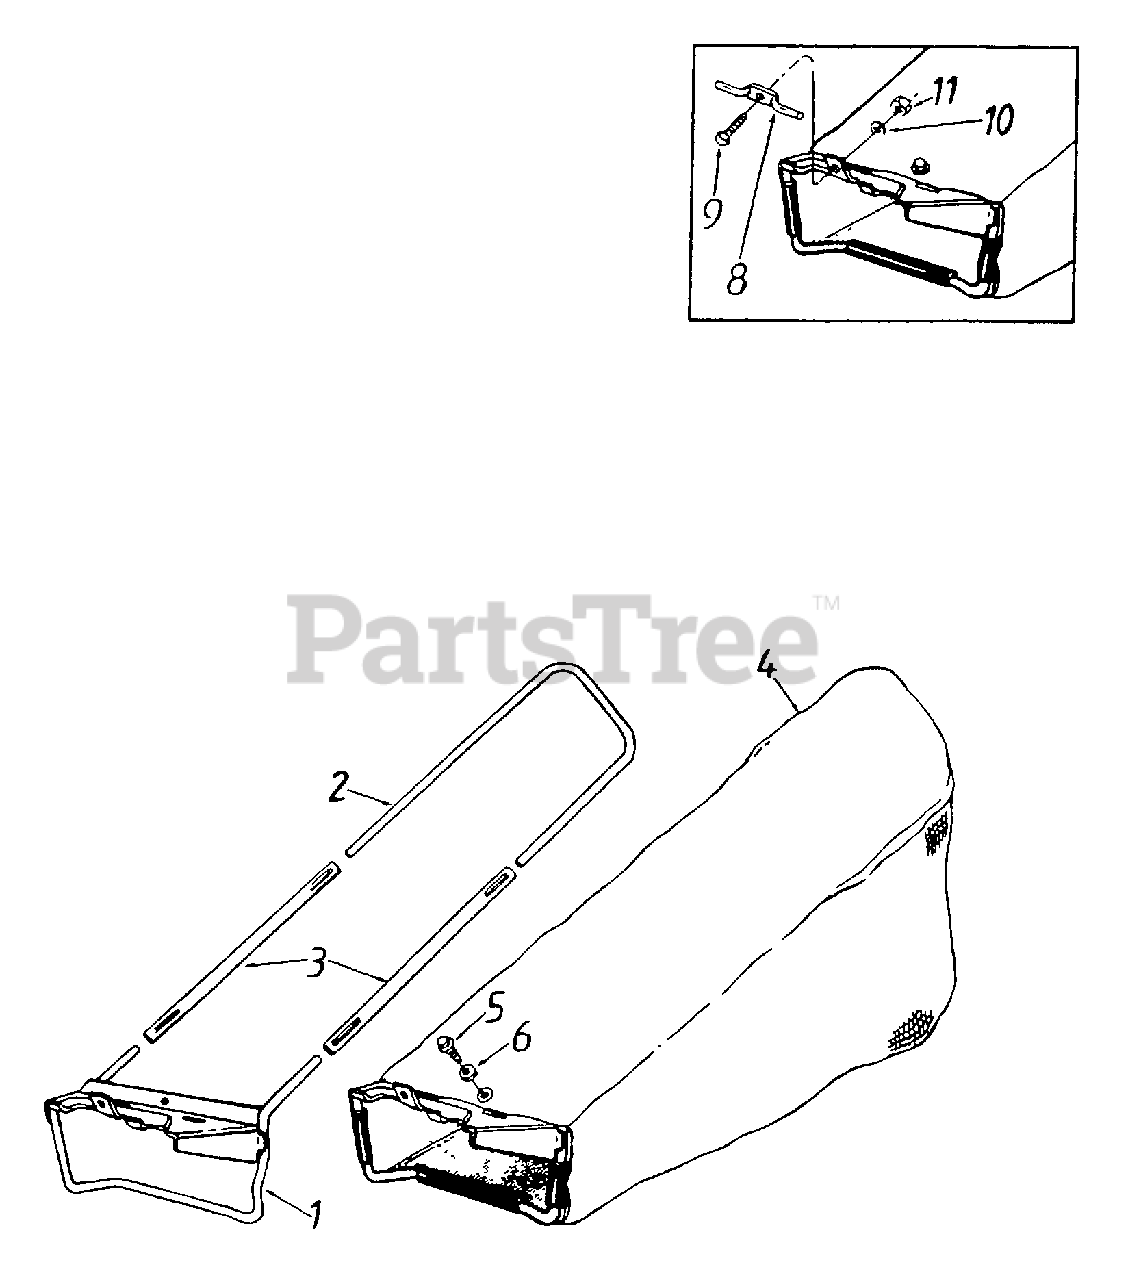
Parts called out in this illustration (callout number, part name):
4	Grass Bag
5	Hex Wash. Hd. TT-Tap Scr. 1/4-20 x 5" Lg.
6	Bell-Wash. 1/4" I.D.
8	Grass Bag Hook
9	Hex Bolt 1/4-20 x .62" Lg.
10	L-Wash. 1/4" I.D.
11	Hex Nut 1/4-20 Thd.
